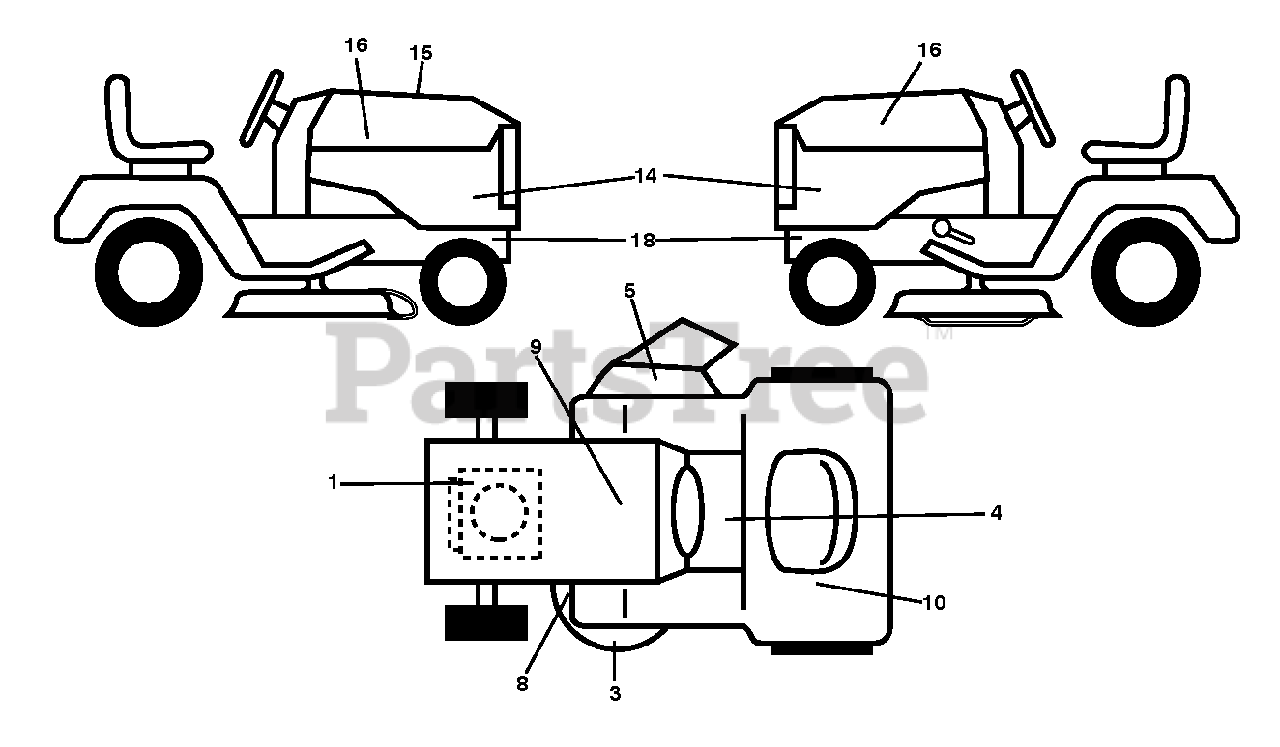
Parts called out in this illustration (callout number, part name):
1	DECAL.ENGINE.WARNING
3	DECAL.DECK.CLEARCUT.NOSTEP
4	Decal, Tractor Saddle
5	DECAL.TRACT/ZTR.DECKWARN.HUSQ
8	DECAL.V-BELT.SCH.42/46"MEC/ELE
9	DECAL BTRY SYMBOLS
10	DECAL.RESERVEFUELSELCTR.ENG
14	Tractor Side Panel Decal
15	Decal, Replacement Kohler KT7 TLB 42F
16	DECAL.BADGE.170MM.TEXTLOGO.
18	DECAL.CHASSIS.HOT.MUFFLER
